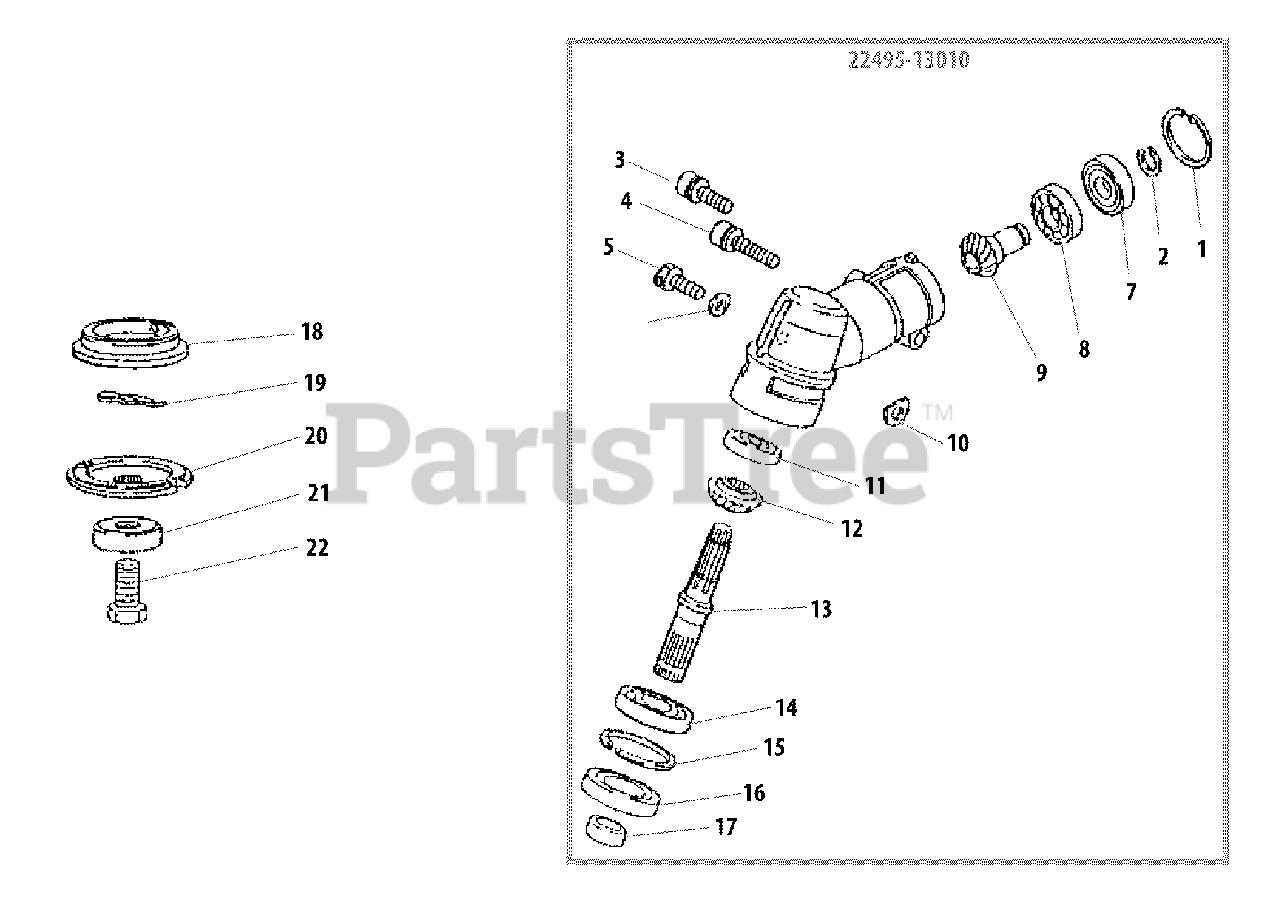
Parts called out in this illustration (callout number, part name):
1	RING, RETAINING - 24
2	RING, RETAINING
3	SCREW - 5X16
4	SCREW - 5X25
5	BOLT - 6X10
6	WASHER - 6
7	BEARING, BALL - 609ZZ
8	BEARING, BALL - 609
9	GEAR SHAFT ASSY
10	SHIM
11	BEARING, BALL - 608DDU
12	GEAR - BEVEL
13	GEAR - SHAFT
14	BEARING, BALL - 6001
15	RING, RETAINING - 28
16	SEAL, OIL
17	COLLAR
18	HOLDER - A
19	CLIP
20	HOLDER (B)
21	GUARD
22	BOLT - 8 -- LEFT HAND
A	GEAR CASE ASSY
